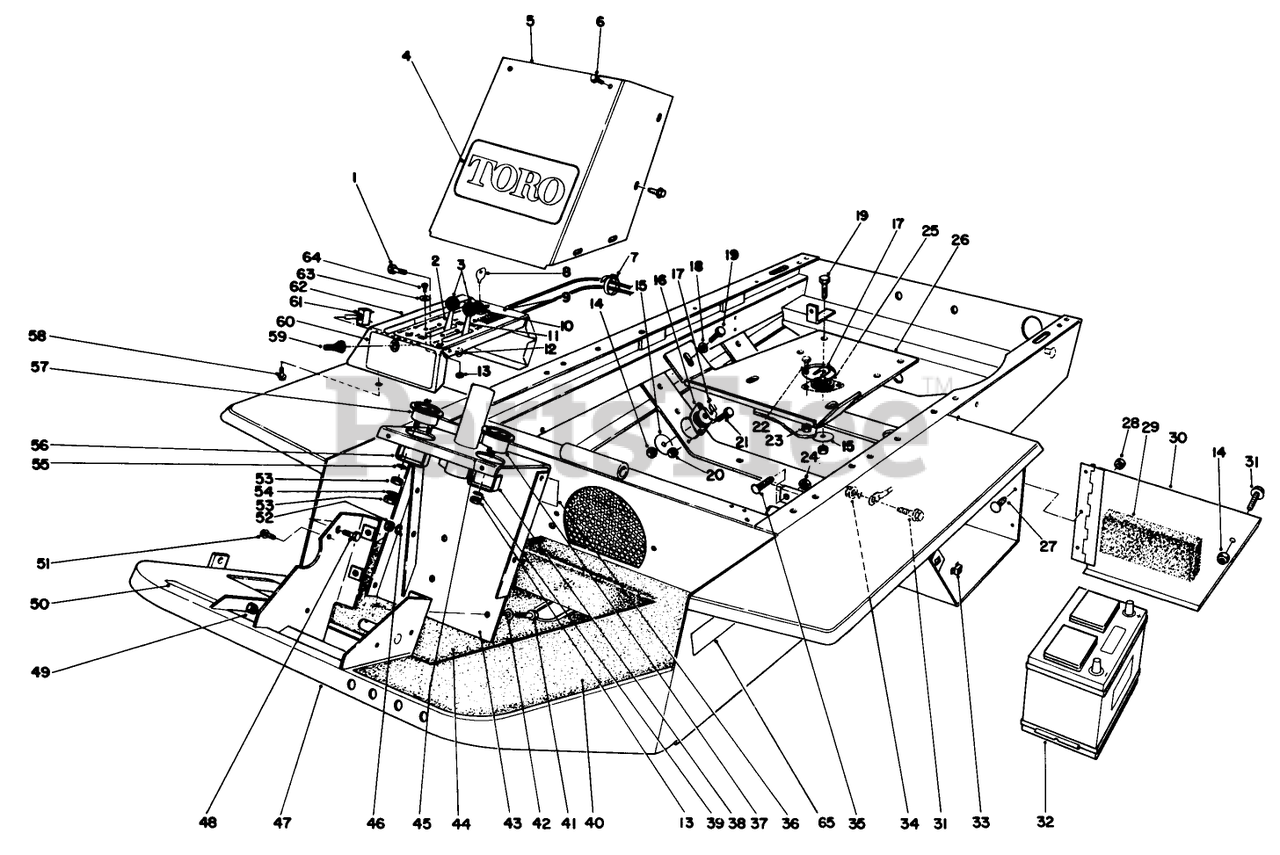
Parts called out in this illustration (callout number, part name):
1	SCREW-HH
2	CHOKE CONTROL
4	DECAL
5	Tower Cover
6	SCREW-HHFTF
7	TIE-CABLE
8	KEY-IGNITION
9	DECAL - INST. PANEL
10	SWITCH
11	THROTTLE CONTROL
12	WASHER-FLAT
13	NUT-HEX
14	NUT-LOCK, NI
15	WASHER
16	ENGINE RUBBER MT
17	SHIM-AXLE
18	WASHER-FLAT
19	SCREW-HH
20	NUT-LOCK, NI
21	SCREW-HH
23	NUT-LOCK, NI
24	NUT-JAM
25	RUBBER MOUNT
26	Base-Engine
27	SCREW-HSBH
28	NUT-LOCK, NI
29	BATT BOX FOAM
30	Battery Cover
31	SCREW-HHF
32	Assembly-Battery
33	RETAINER NUT
34	NUT-HHF, WHIZ
35	SCREW-CARR
36	DECAL-OIL
37	HOUR METER
38	BRACKET F/W
39	WASHER-LOCK, INT
40	NON SKID (TUNNEL)
41	SCREW-HH
42	WASHER-LOCK
43	Steering Post
44	NON-SKID-FLOOR
45	INSTRUCTION DECAL
46	WASHER-LOCK
47	FRAME WA
48	SCREW-HH
49	NUT-LOCK, NI
50	DECAL-PEDAL, TRACTION
51	SCREW-HWH
52	NUT-HEX
53	NUT-HEX
54	WASHER-LOCK
55	WASHER-FLAT
56	MTG CLAMP F/W GUAGE
57	AMMETER GAUGE ASSY
58	SCREW-THD FRM,HWH
59	BOOT-SWITCH
60	BY-PASS DECAL
61	Switch-Toggle (Incl. Ref. #58)
62	Instrument Panel
63	WASHER-LOCK
64	10-24 X 5/8 PAN HD MS
65	CAUTION DECAL
